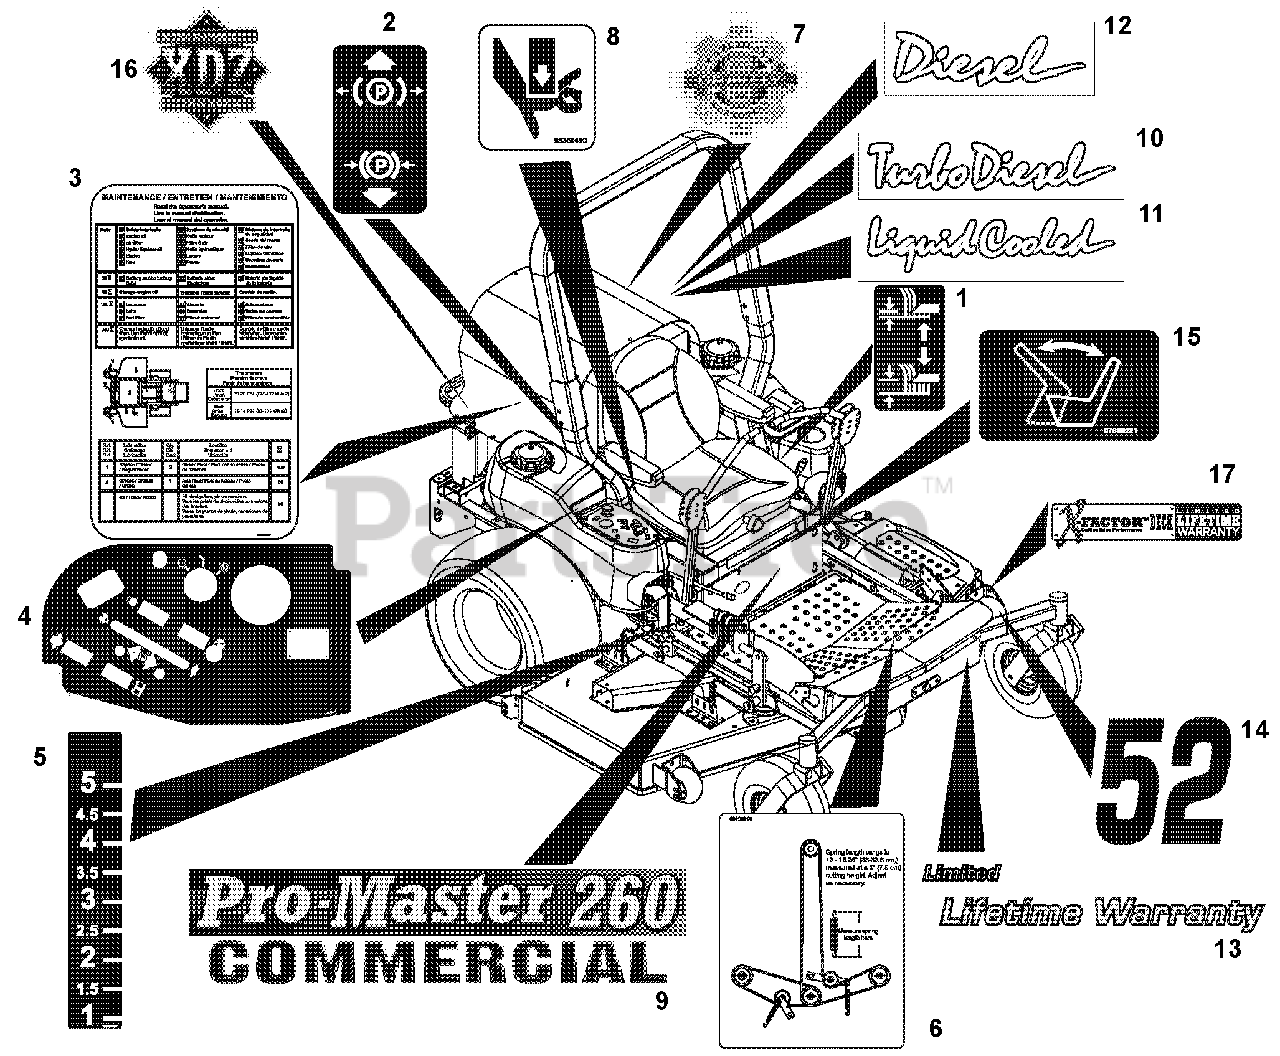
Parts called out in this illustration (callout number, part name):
1	Decal, Lift Lever
2	Decal, Parking Brake Lever
3	Decal, Maintenance Instructions
4	Decal, Control Panel, Diesel
5	Decal, Height of Cut
6	Decal, Belt Routing (992316, 317, 321, 322, 324)
7	Decal, Gravely Heritage – Large
8	Decal, Pinch Point
9	Decal, PM260Z (992316, 317, 324)
10	Decal, Turbo Diesel (992317, 321)
11	Decal, Liquid Cooled
12	Decal, Diesel (992316, 322, 324)
13	Decal, Limited Liffetime Warranty (992316, 317, 321, 322)
14	Decal, 60" (992316, 317, 324)
15	Decal, Seat Release
16	Decal, XDZ 5"
17	Decal, X-Factor (992324)
